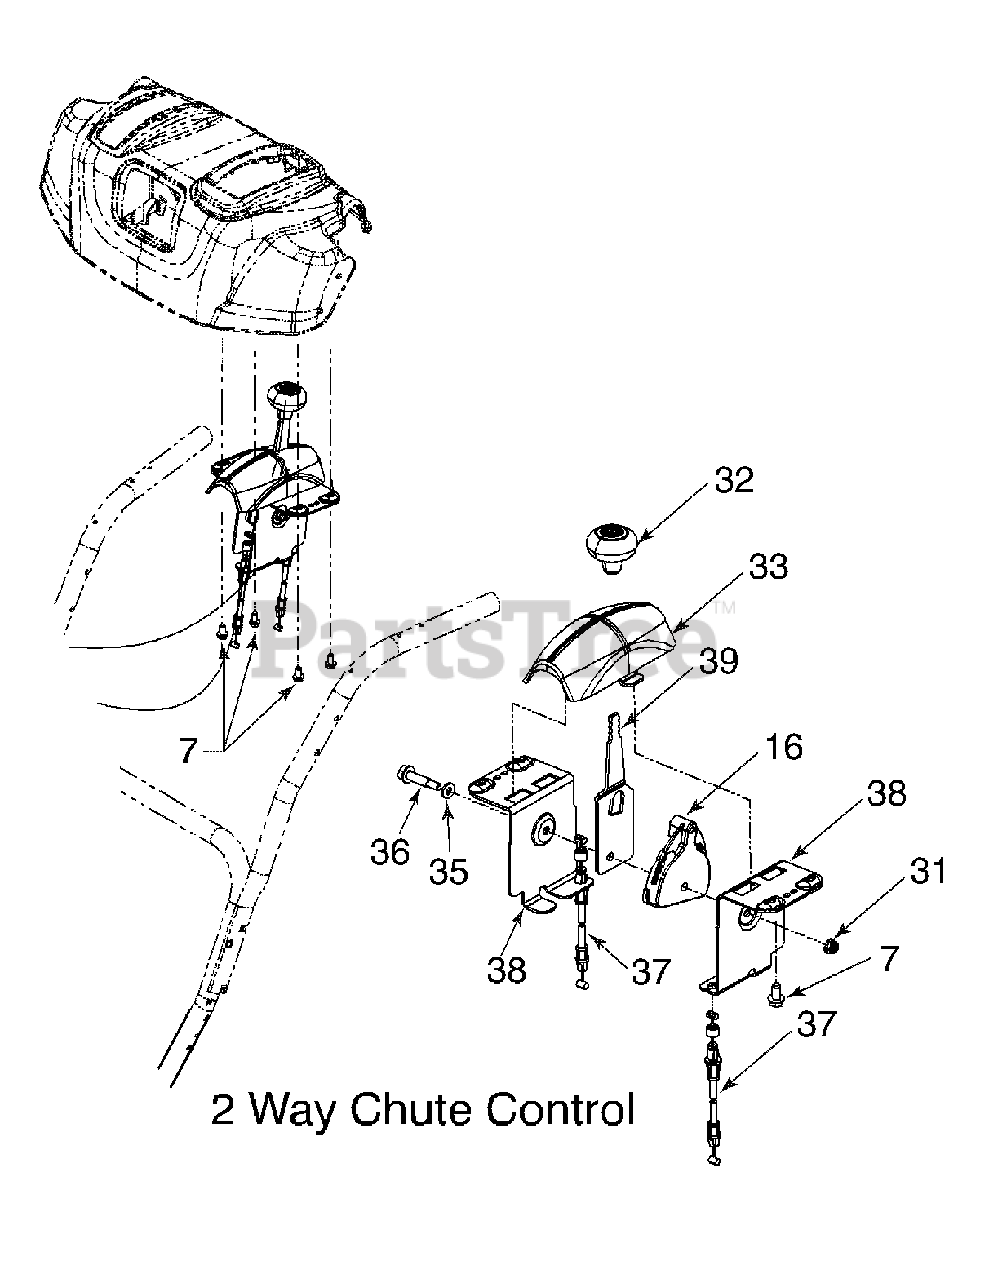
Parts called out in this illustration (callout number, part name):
7	Hi-Lo Screw 1/4-15 x .5
16	Cable Guide
31	Flange Locknut 1/4-20 Gr. F, Nylon
33	Control Cover - 2 Way
35	Spring Washer .390 x .625 x .012
36	Screw, Shoulder .310 x .995 x 1/4-20
37	Cable Chute Tilt - 2 Way 900
38	Mounting Bracket - 2 Way
